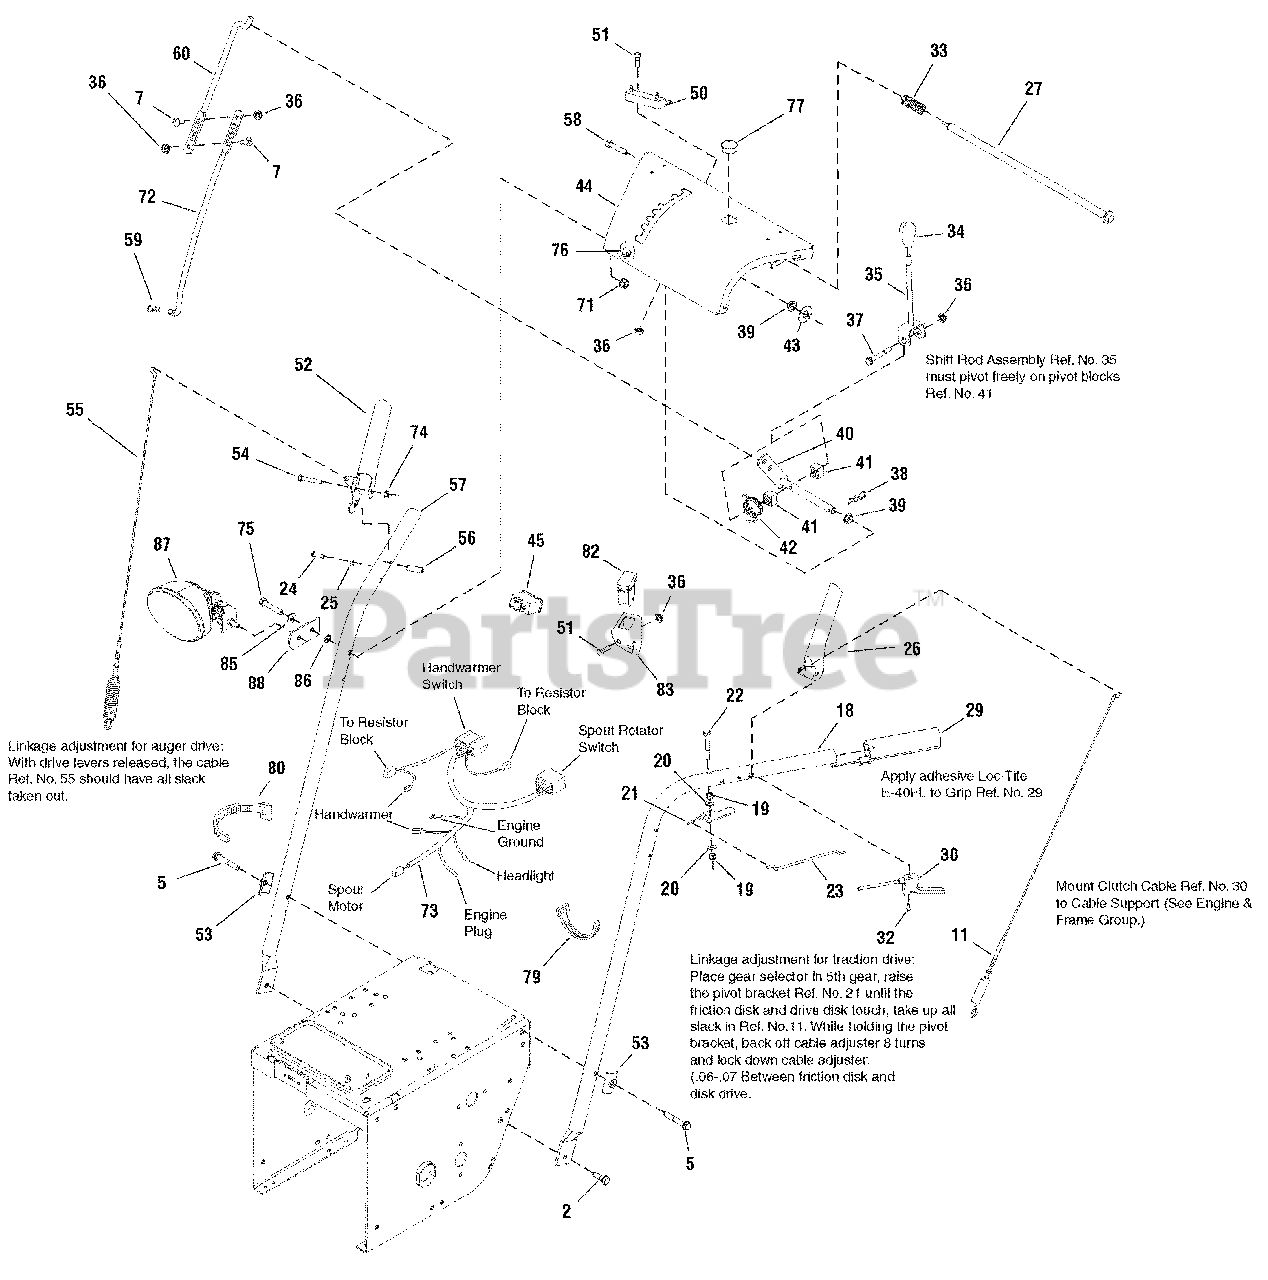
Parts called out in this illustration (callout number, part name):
2	SCREW, Hex Head Serrated Flange Taptite, 5/16-18 x 1
5	SCREW, Hex Head Serrated Flange Taptite, 5/16-18 x 2
7	CARRIAGE BOLT, 1/4-20 x 3/4, G5
11	CABLE & SPRING ASSEMBLY
18	HANDLE, Tube L.H. 2006 Snow
19	NUT, Hex Lock ESNA Light, 1/4-20 NC3B
20	WASHER, 1/4, .27 ID x .62 OD x .05 THK
21	LEVER, Pivot
22	CAPSCREW, Hex Head, 1/4-20 x 2, G5
23	ROD, Hold Down
24	SCREW, Pan Head Torx Taptite, 1/4-20 x 3/4
25	SPACER
26	GRIP, Clutch L.H., Plastisol Dip
27	ROD with PIN ASSEMBLY
29	HAND GRIP, Heated
30	CABLE & HANDLE ASSEMBLY
32	SCREW, Pan Head Torx, #10 x 1/2 THK
33	SPRING, Compression
34	KNOB, Tapered, 3/8 Internal Thread
35	ROD & CLEVIS ASSEMBLY
36	NUT, Hex Keps, 1/4-20 Conical Washer
37	SCREW, Hex Whiz Lock Flange, 1/4-20 x 2-1/4
38	CLIP, Hair Pin, .093 DIA, 1-5/8 LG
39	BUSHING, 1/2 ID x 3/4 OD x 1/4 LG Nylon
40	PIVOT ASSEMBLY
41	BLOCK, Pivot
42	SPRING, Compression
43	WASHER, 1/2, .53 ID x 1-1/4 x .08 THK
44	DASH ASSEMBLY
45	SWITCH, Hand Warmer
50	RESISTOR
51	CAPSCREW, Hex Head, 1/4-20 x 3/4, G5
52	GRIP, Clutch R.H., Plastisol Dip
53	CLAMP, Saddle, Snow Handle E-Coat
54	CAPSCREW, Hex Head, 1/4-20 x 1-1/2, G5
55	CABLE & SPRING ASSEMBLY
56	SPACER, .259 ID x .377 OD x 1.1 LG
57	HANDLE, Tube R.H. 2006 Snow
58	CAPSCREW, Hex Head, 5/16-18 x 1-1/2, G5
59	PIN, Quick
60	ROD, 3/8 DIA 11.38 LG
71	NUT, Hex Flange, 5/16-18 ESNA
72	ROD, Shift Lower
73	HARNESS, Hand Warmers/Spout Snow 2006
74	NUT, Hex Centerlock, 1/4-20
75	CAPSCREW, Hex Head, 5/16-18 x 1-3/4, G5
76	CLIP, Wire
77	PLUG, Button for .437 DIA Hole, Plastic
79	TIE, Self-Locking, .184 WD 7.31 LG
80	TIE, Self-Locking, .184 WD 15 LG
82	SWITCH, Rocker Chute Rotator, Snow 5 Pin
83	SUPPORT, Switch, 14GA WB Snow
85	WASHER, 5/16, .34 ID x 3/4 OD x .06 THK
86	LOCKWASHER, External Tooth, 5/16
87	HEADLIGHT ASSEMBLY, Oval Clear 2007 Snow
88	BRACKET, Headlight, 10GA Pro Snow
